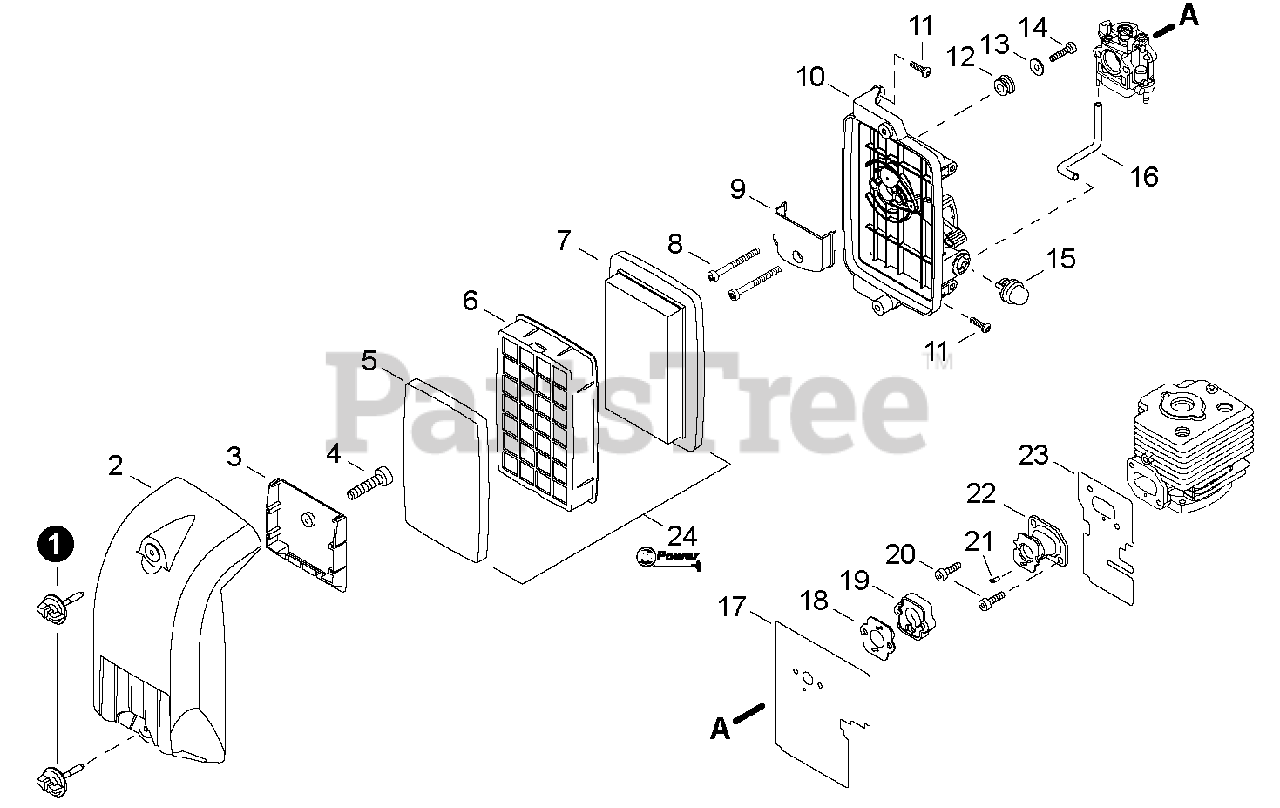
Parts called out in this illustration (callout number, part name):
1	THUMBSCREW
2	COVER, AIR FILTER
3	SUPPORT, PRE-FILTER
4	SCREW - 4X12
5	PRE-FILTER -- FOAM
6	RETAINER, PRE-FILTER
7	FILTER, AIR
8	SCREW - 5X55
9	PLATE, PREVENT
10	CASE, AIR FILTER
11	SCREW - 5X20
12	GUIDE, CABLE
14	SCREW - 5X16
15	PUMP, PURGE
16	PIPE - 3X5X140 -- BLACK
17	SHIELD, INTAKE
18	GASKET, INTAKE
19	ADAPTOR, INTAKE
20	SCREW - 5X12
21	ADAPTOR
22	BELLOWS, INTAKE
23	GASKET, INTAKE
24	RePower TUNE-UP KIT
